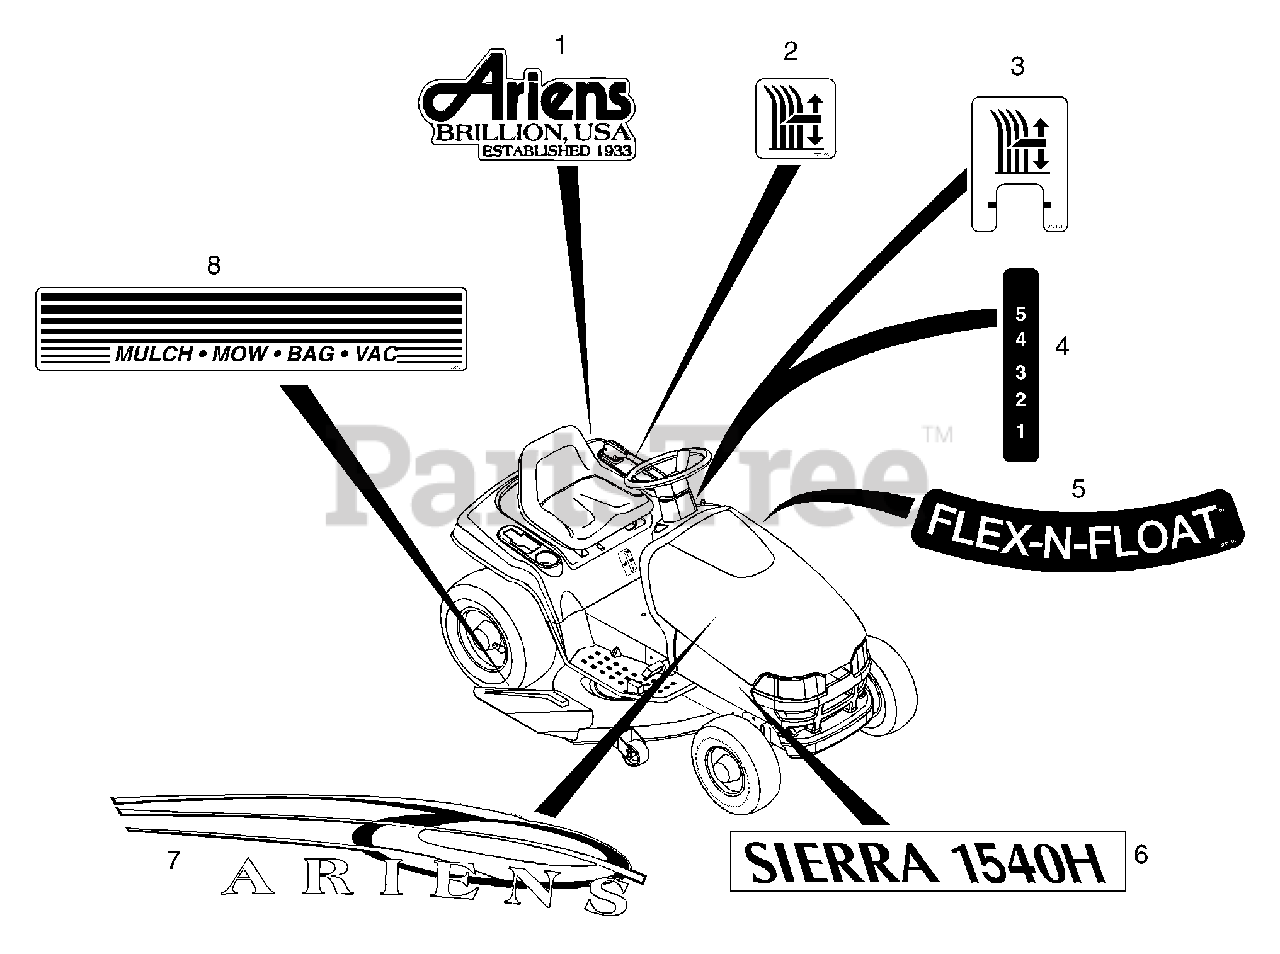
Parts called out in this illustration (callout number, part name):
1	DECAL- ARIENS EST. 1933
2	DECAL - CUT HEIGHT - INSERT
3	DECAL - CUT HEIGHT - FRAME
4	DECAL - INDICATOR 5 POS
5	DECAL FLEX-N-FLOAT
6	DECAL - SIERRA 1540G - R
7	DECAL ARIENS HOOD LOGO RIGHT
8	DECAL- MULCH-MOW-BAG-VAC
